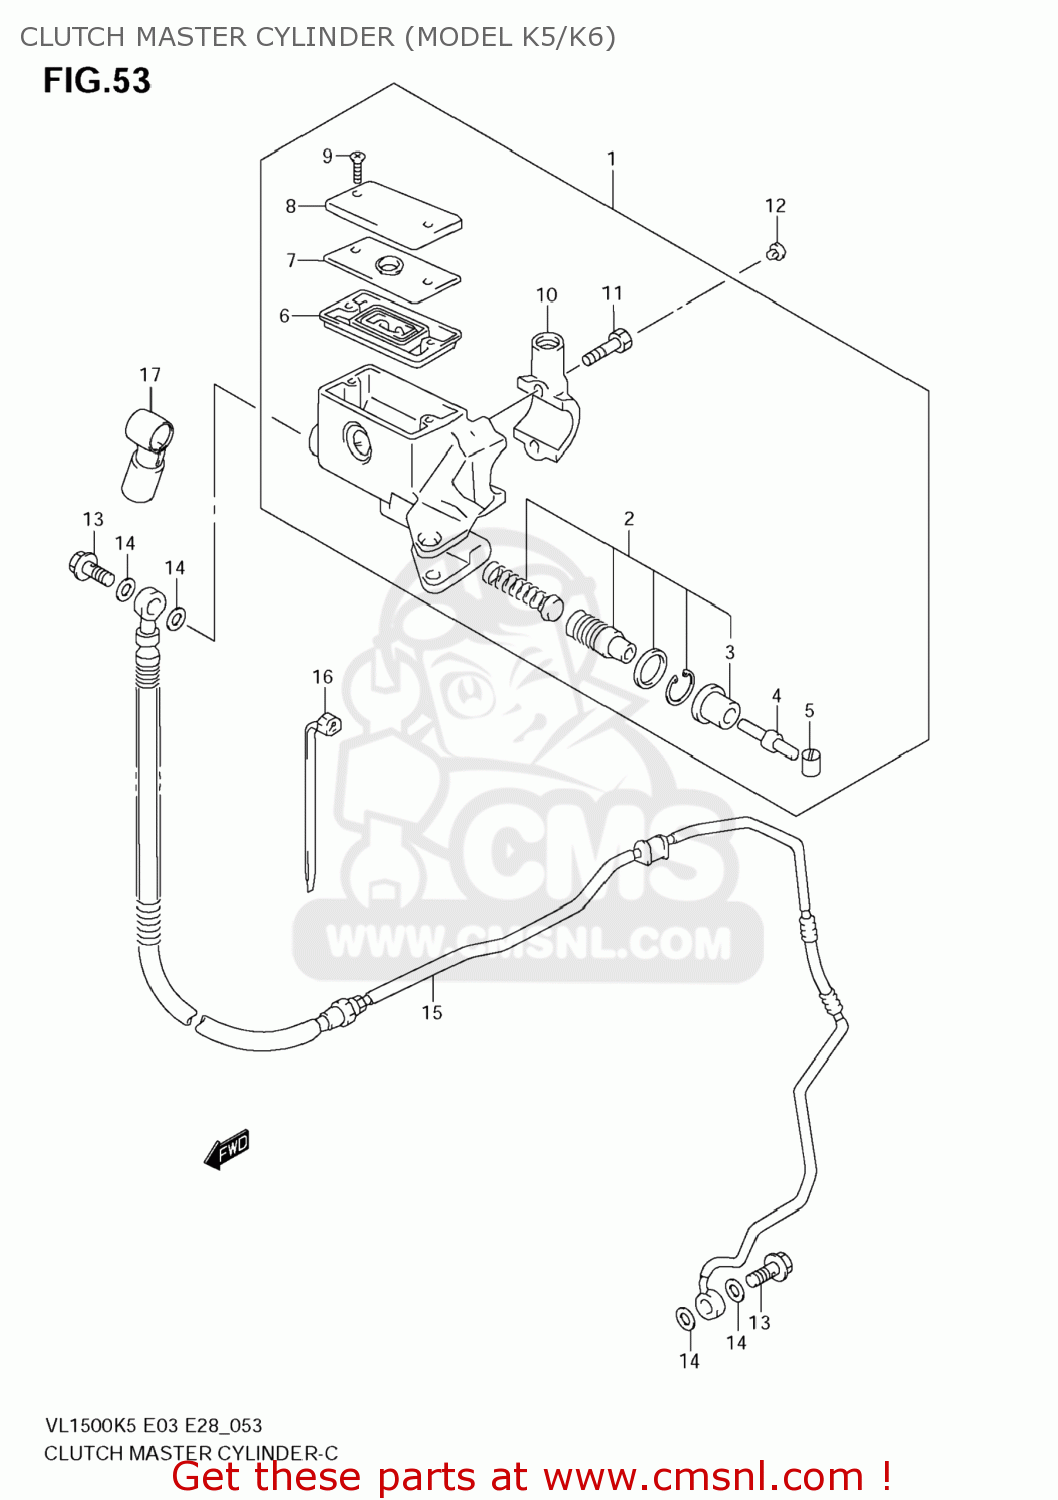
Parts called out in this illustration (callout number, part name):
1	CYLINDER ASSY,CLUTCH MASTER
2	PISTON & CUP SET
3	BOOT
4	ROD,PUSH
5	BUSH
6	7
7	PLATE,DIAPHRAGM
8	CAP
9	SCREW
10	HOLDER
11	BOLT
12	CAP(OD:10)
13	BOLT UNION
14	WASHER(10X15X1.5)
15	HOSE ASSY,CLUTCH
16	CLAMP(L:235)
17	BOOT,MASTER CYLINDER
